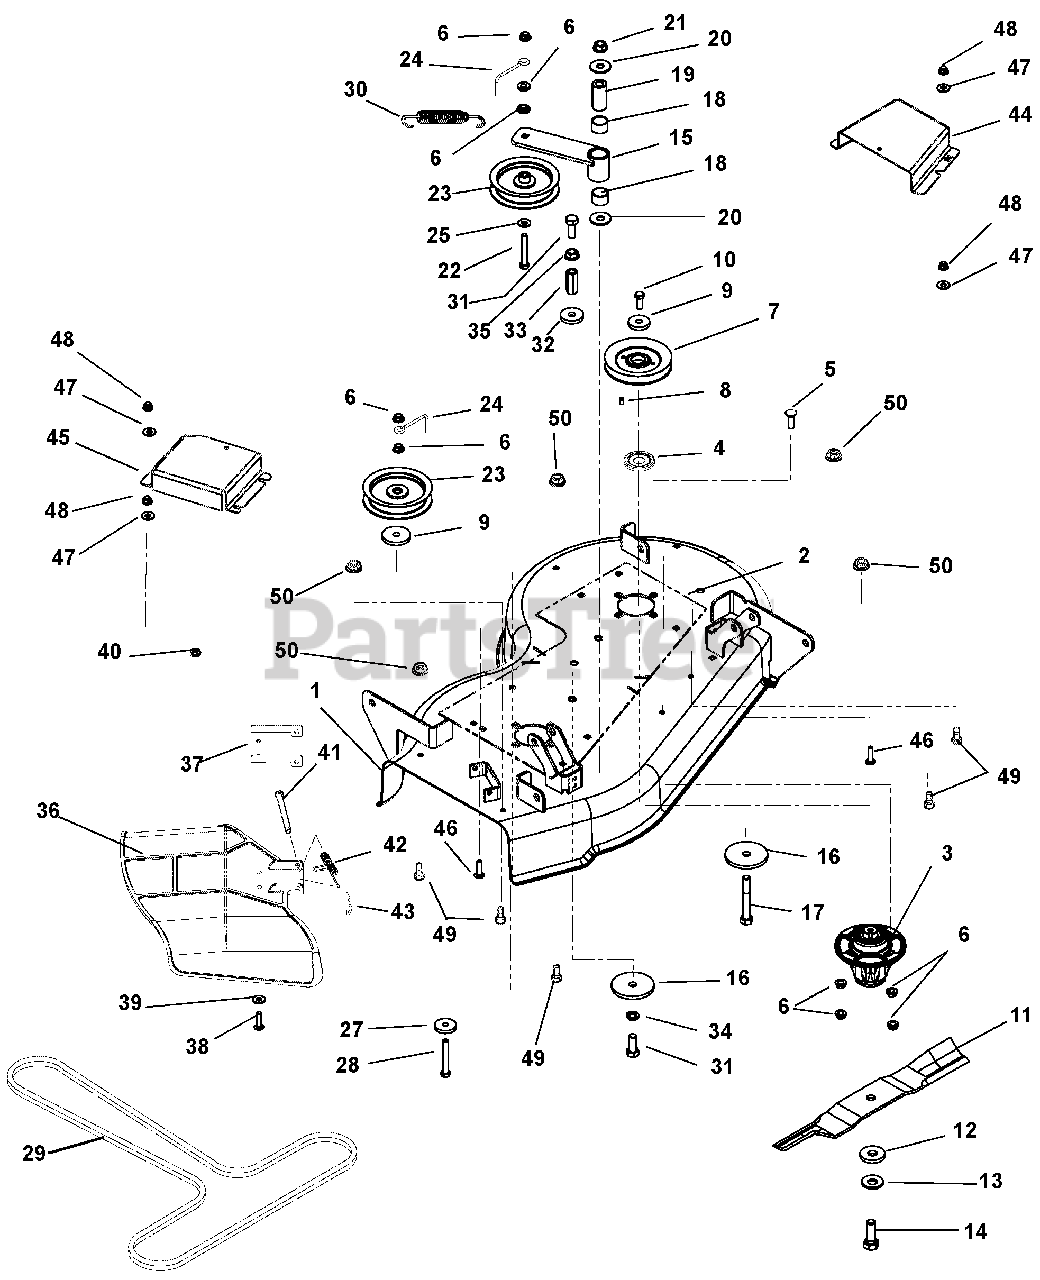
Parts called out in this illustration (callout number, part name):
1	WMT, 34" STAMPED DECK (ARIENS)
2	DOUBLER PLATE, 34" DECK
3	SPINDLE ASSEMBLY
4	DUST CAP
5	@BLT-RDHDSQNK .38-16X1.25 G5YZ
6	@NUT-LK-NYL-FLG .38-16 YWZC
7	SHEAVE, 4.75 DIA A-SECTION
8	KEY, SQ .25 X .38 X .25
9	WSHR,FLT STL.406X1.50X.245YWZC
10	BLT-HEX .38-16X1.0 GR8 YZ EP30
11	BLADE, 17.38X2.5X.204
12	WSHR-FLT .640X1.75X.250 YWZC
13	WSHR-BLVL .669X1.535X.138
14	BLT-HEX .62-18X1.75 GR8 YWZC
15	WELDMENT, IDLER ARM
16	WSHR-FL-STL .515X1.625X.250 YZ
17	@BLT-HEX .50-13X3.50 GR5 YWZC
18	BRG, 1.00 X 1.12 X .75
19	BSHG, SPCR .502X.997X2.03 PM
20	WSHR-FL-STL.511X1.441X.125 YWZ
21	@NUT-LK-TOP-FLG .50-13 YWZC
22	@BLT-HEX .38-16X2.50 GR5 YWZC
23	IDLER, FLAT .38X4.00X1.06
24	BELT FINGER
25	BSHG-FLG .406X.88X.270X.140
26	WSHR,FLT STL.406X1.50X.245YWZC
27	WSHR-FL-STL .469X2.00X.25 YWZC
28	@BLT-HEX .38-16X2.75 GR5 YWZC
29	V-BELT, HA-WRAPPED
30	EXTENSION SPRING
31	@BLT-HEX .50-13X1.25 GR5 YWZC
32	WSHR-FL-STL .515X1.625X.250 YZ
33	NUT, COUPLING 1/2-13X1.75 YWZC
34	@WSHR-LK .50X.125 REG YWZC
35	NUT-SPNLK-FLG .50-13 YWZC
36	MOLDED CHUTE, ZOOM
37	CHUTE REINFORCEMENT
38	SCR-SKH .31-18X.75 BTNHD YWZC
39	@WSHR-FL-STL.38X.875X.083 YWZC
40	@NUT-LK-TOP-FLG .31-18 YWZC
41	PIN, 5/16 X 3.88"
42	SPRING, TORSION
43	PIN-HAIR INT .08X.18X1.18 YWZC
44	BELT COVER, 34" LEFT
45	BELT COVER, RIGHT
46	@BLT-RHDSHSQNK.31-18X1.25 G5YZ
47	@WSHR-FL-STL.38X.875X.083 YWZC
48	@NUT-LK-NYL-FLG .31-18 YWZC
49	@BLT-HEX .31-18X.75 GR5 YWZC
50	@NUT-SPNLK-FLG .312-18 YWZC
